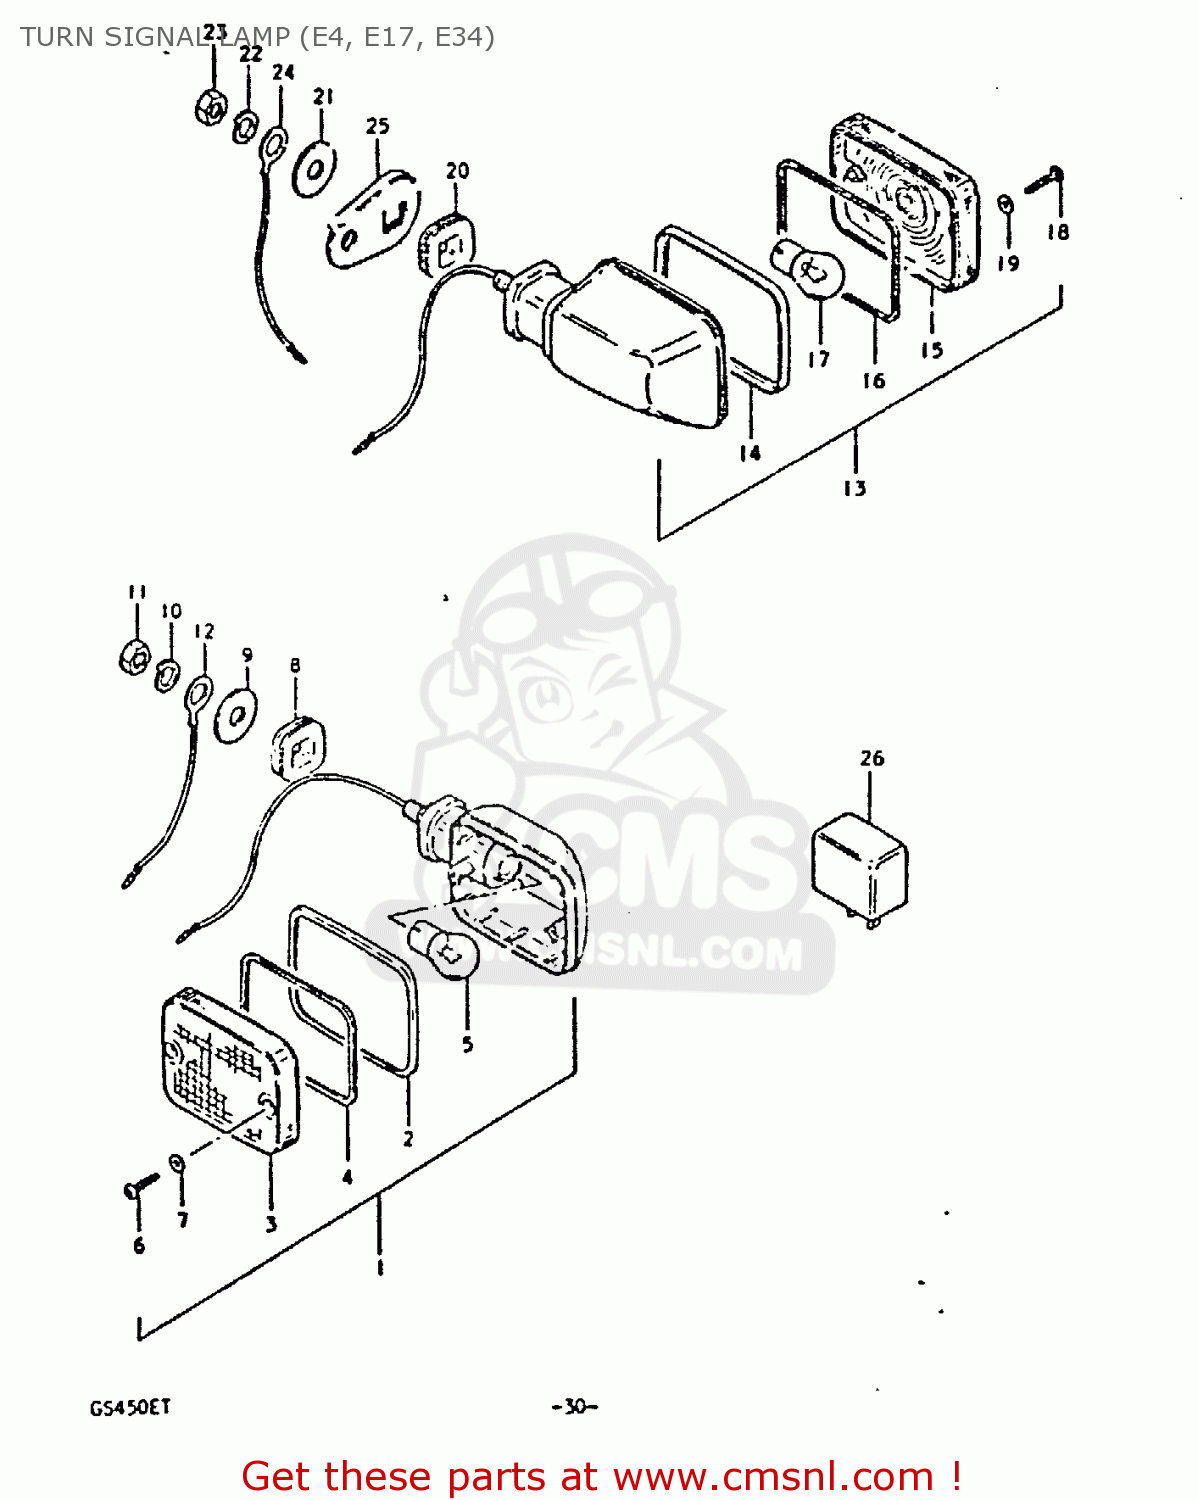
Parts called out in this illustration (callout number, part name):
1	LAMP, FRONT TURN SIGNAL
2	RIM
3	LENS
4	GASKET (NAS)
5	BULB 12V 21W
6	SCREW
7	GASKET (NAS)
8	CUSHION
9	WASHER (10.5X30X2.3)
10	LOCK WASHER
11	NUT
12	LEAD WIRE,EARTH
13	LAMP, FRONT TURN SIGNAL
14	RIM
15	LENS
16	GASKET (NAS)
17	BULB 12V 21W
18	SCREW
19	GASKET (NAS)
20	CUSHION
21	WASHER (10.5X30X2.3)
22	LOCK WASHER
23	NUT
24	LEAD WIRE,EARTH
25	BRACKET,RR TURN SIGNAL LAMP
26	RELAY,TURN SIGNAL
